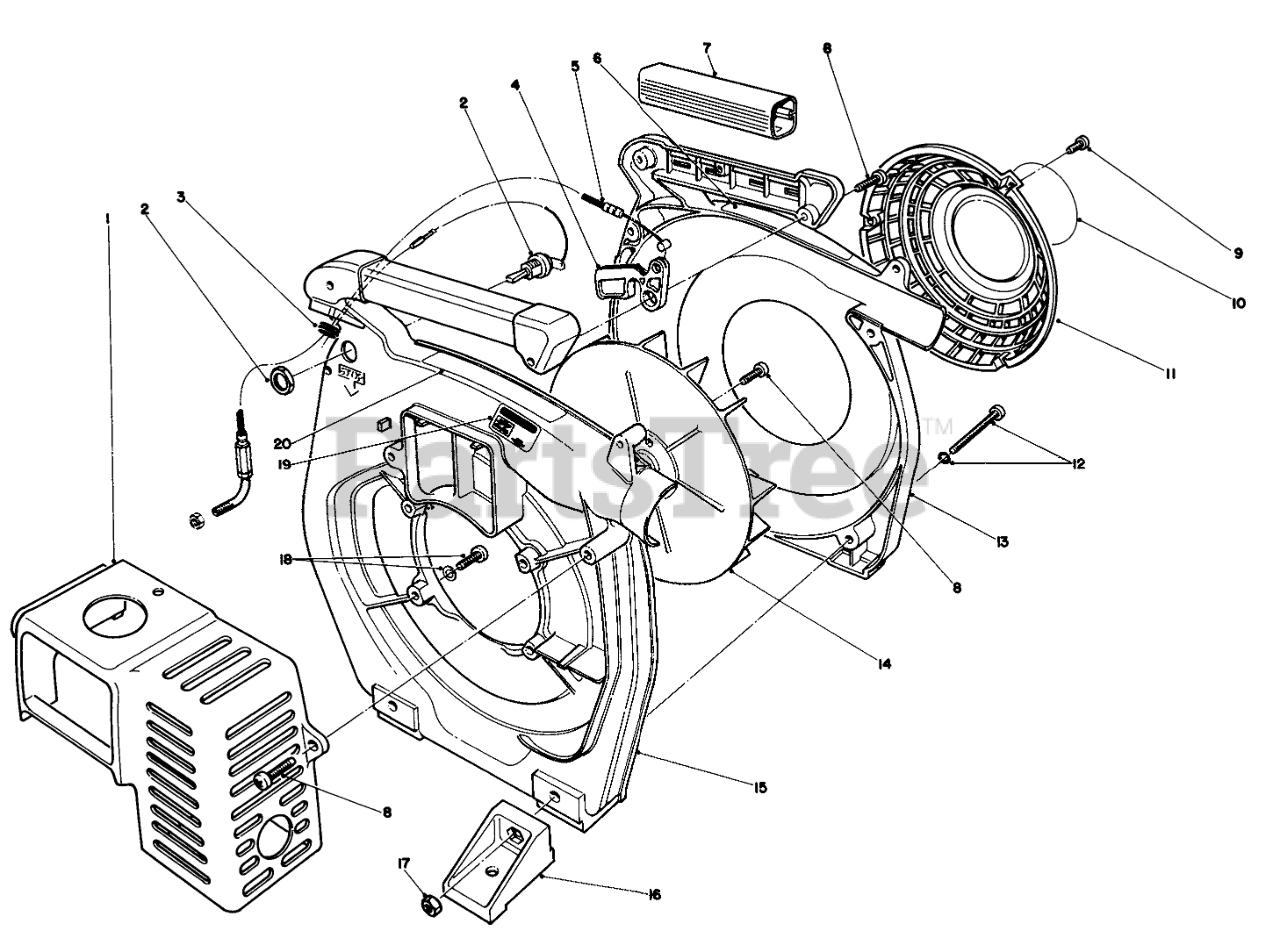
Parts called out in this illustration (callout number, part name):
1	ENGINE COVER
2	Switch Assembly
3	GROMMET
4	THROTTLE LEVER
5	THROTTLE WIRE
6	Decal-Instruction
8	SCREW
9	SCREW
10	Decal-Toro
11	Screen Assembly, Inlet (Incl. Ref. #10)
12	SCREW ASSEMBLY
13	Case-Front (Incl. Ref. #6)
14	IMPELLER
15	Case-Rear (Incl. Ref. #19 & 20)
16	Bracket-Stand
17	INSULATOR NUT
18	SCREW ASSEMBLY
19	Decal-Hot Surface
20	Decal-Danger
